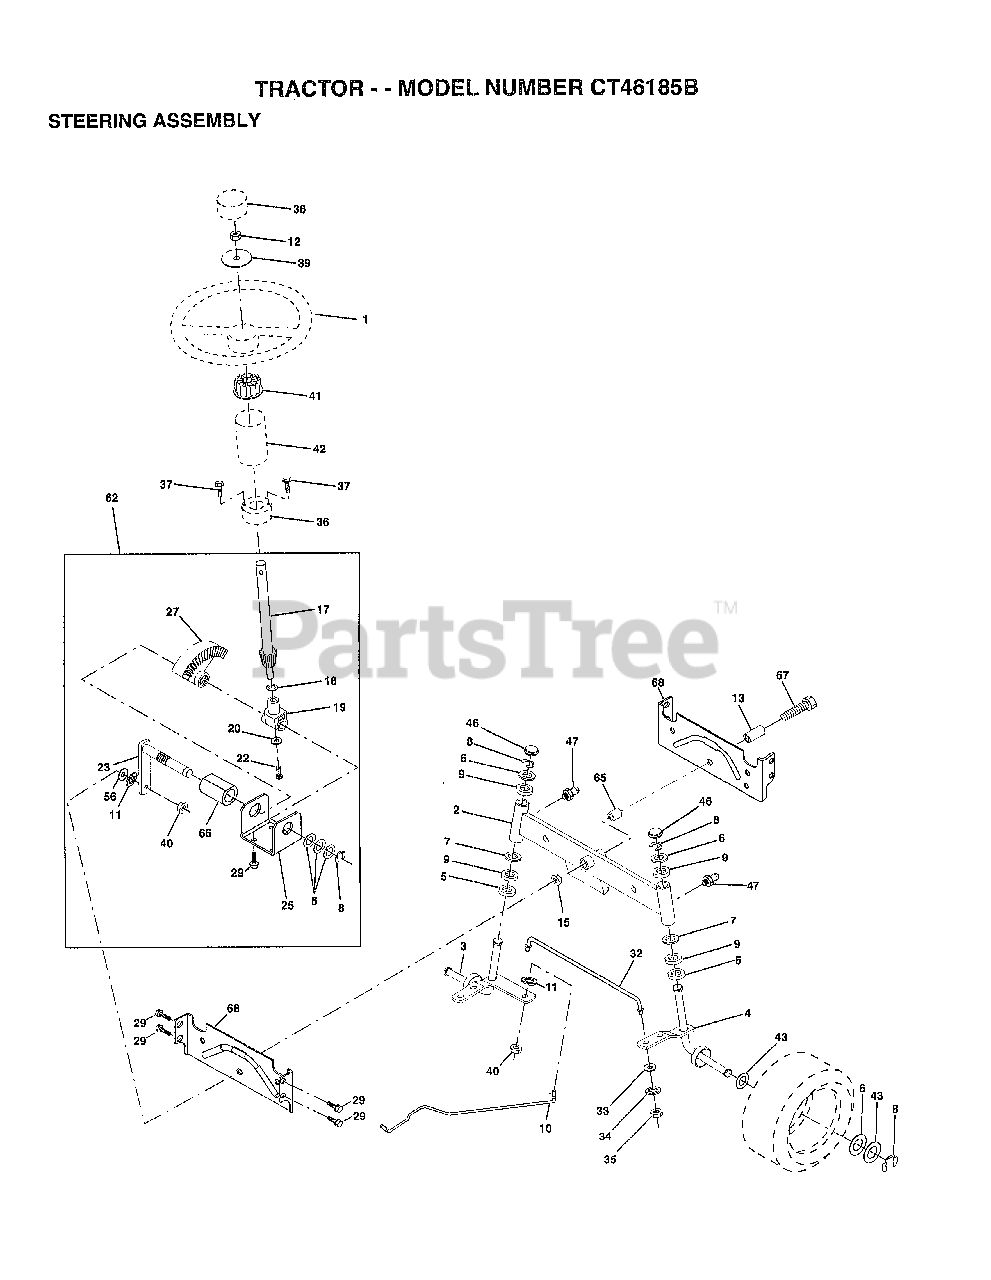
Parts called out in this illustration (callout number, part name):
1	WHEEL STR AYP BLK
2	AXLE ASM
3	"SPINDLE ASM,RH"
4	"SPINDLE AMS,LH"
5	WASHER .T
6	WASHER
7	WASHER
8	RING
9	COL. SRTG. BEAR.
10	DRAGLINK-STAMPED
11	LOCKWASHER
13	BEARING AXLE
15	"NUT-LOC,FLANGE LT"
17	SHAFT ASM STEERNG
18	THRUST WASHER
19	SUPPORT.SHAFT
22	SCREW HEX SOC1/4-
25	BRKT-STEERING
27	GEAR SECTOR
29	SCREW
32	ROD.TIE.19.75
33	WASHER M
34	LOCKWASHER
35	NUT.LOCK.5/16-24
36	BUSHING.STRG.3/4
37	"SCREW-TT,10-32 FL"
38	CAP STEER AYP
39	WASHER
40	GRIPCO NUT
41	ADAPTER LT
42	BOOT SHAFT STEER
46	CAP
47	ZERK M
56	WASHER
62	KIT STEERING ASM
65	SPACER AXLE
66	"BEARING-ARM,PITMA"
67	BOLT
68	BRACE AXLE
